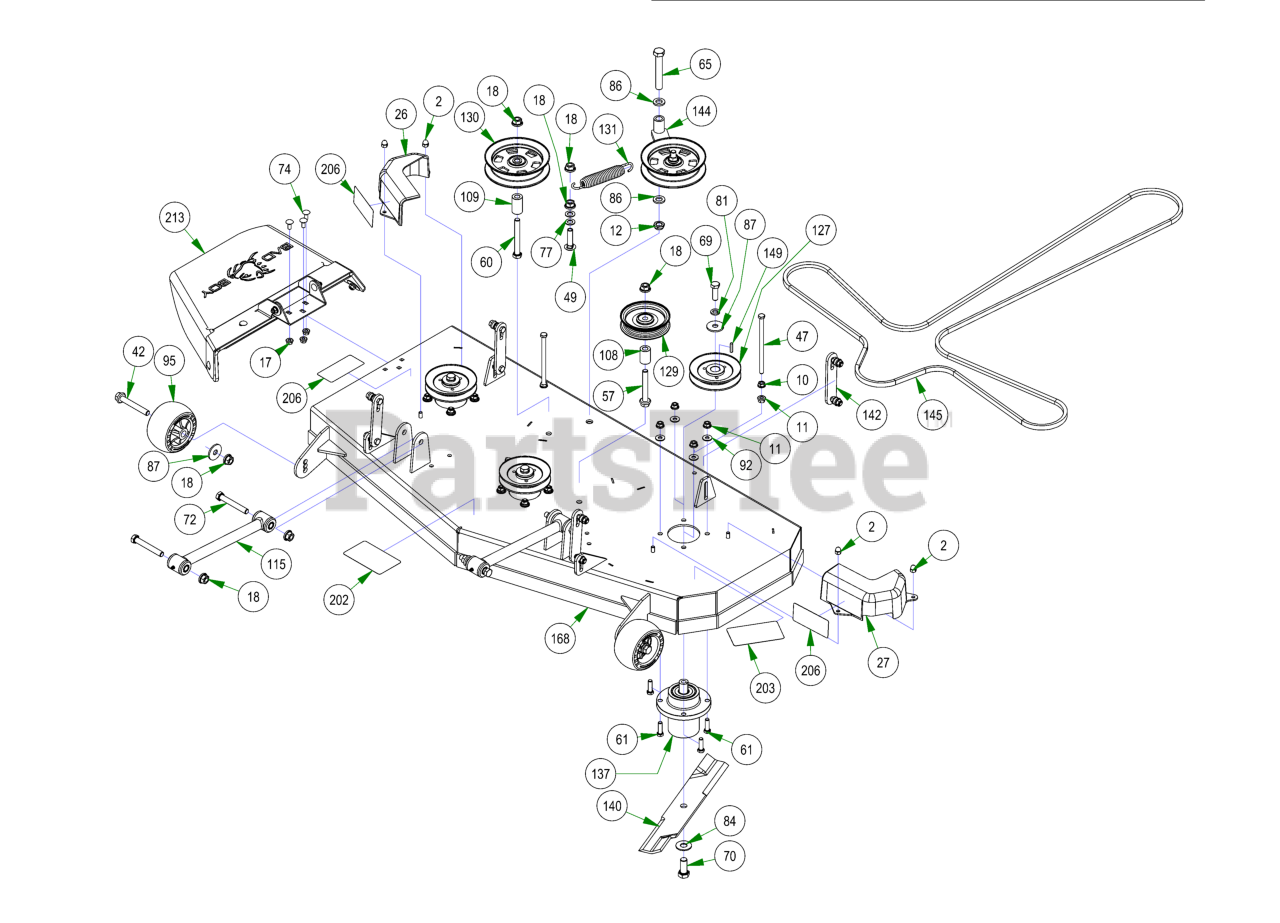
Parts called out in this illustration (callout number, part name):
2	5/16-18 ACORN NUT HIGH-CROWN ZC
10	3/8-16 HEX SERRATED FLANGE NUT HARD/ZINC
11	3/8-16 NYLON INSERT FLANGE LOCKNUT (GR.F) ZINC
12	5/8-11 NYLON INSERT JAM LOCKNUT ZINC
17	5/16-18 NYLON INSERT FLANGE LOCKNUT ZINC
18	1/2-13 NYLON INSERT FLANGE LOCKNUT ZINC
26	pulley cover chute side
27	pulley cover non-chute side
42	1/2-13 X 90MM HEX FLANGE BOLT W/SHOULDER (GR.8) ZINC
47	3/8-16 X 6.5 HEX CAP SCREW (GR.5) ZINC
49	1/2-13 X 2 CARRIAGE BOLT ZINC
57	1/2-13 X 3-1/2 HEX FLANGE BOLT (GR.8) ZINC
60	1/2-13 X 4 HEX CAP SCREW (GR.8) ZINC YELLOW
61	3/8-16 X 1-1/4 HEX CAP SCREW (GR.5) ZINC
65	5/8-11 X 4 HEX CAP SCREW (GR.8) ZINC YELLOW
69	1/2-20 X 1-1/2 HEX CAP SCREW (GR.5) ZINC
70	5/8-18 X 1-1/2 HEX CAP SCREW (GR.8) ZINC YELLOW
72	1/2-13 X 3-1/2 HEX CAP SCREW (GR.5) ZINC
74	5/16-18 x 3/4 Carriage Bolt
77	.517 SQ WDTH ID X .937 OD X .060 THICK F/W PHOS/OIL
81	1/2 SPLIT LOCKWASHER (GR.8) ZINC/YELLOW
84	5/8 USS FLAT WASHER (1-3/4" OD) GR.8 ZINC YELLOW
86	.635 ID X 1.120 OD X .140 THICK FLAT WASHER NYLON
87	1/2 BELLEVILLE WASHER (1-5/8 OD X .140 THK) ZINC
92	5/16 USS FLAT WASHER (7/8 OD) ZINC
95	Deck Wheel
108	.502 ID X .750 OD X 1.500 Long Spacer
109	1 3/4" Pulley Spacer
115	Hybrid Turnbuckle/Deck Locator
127	MZ Deck Pulley
129	4 3/4" Idler Pulley
130	5-3/4 Idler Pulley
131	Deck Idler Spring
137	Spindle Assembly-MZ
140	48" High Lift Fusion Blade
142	Deck Hanger Assembly
144	2017 54"/48" Deck Idler Assembly
145	B147 Deck Belt
149	3/16 X 1 SQ MACHINERY KEY 1018 STL ZINC
168	48" Welded Deck Shell
202	2017 MZ Magnum 48"/42" Deck Route Decal
203	2018 48" Deck Decal
206	Danger Decal-Spindle/Discharge
213	MZ Discharge Chute Assembly
